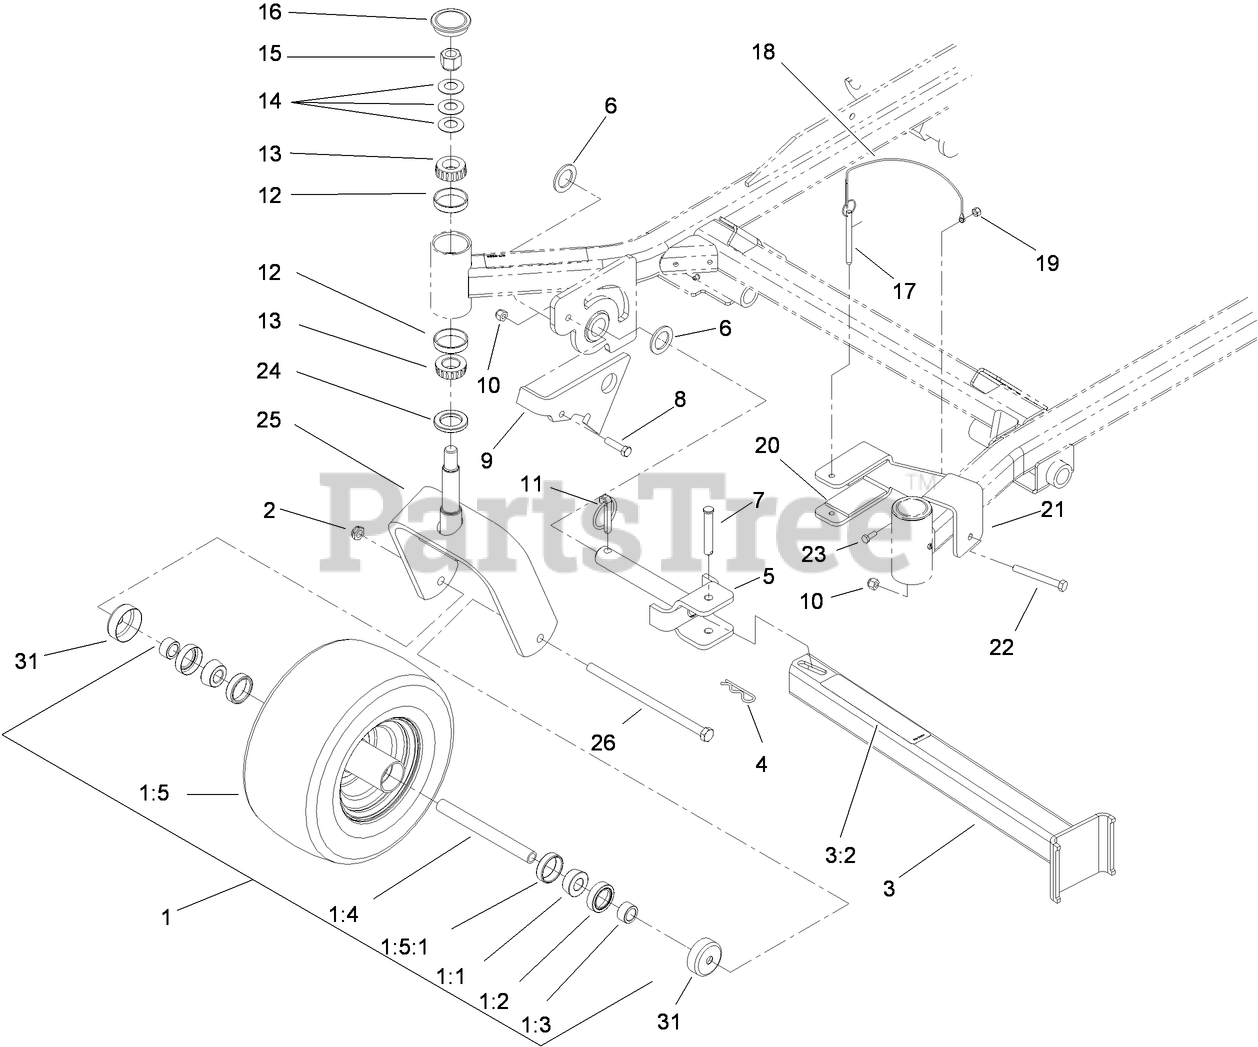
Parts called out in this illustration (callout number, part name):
1	WHEEL AND TIRE ASM
1:1	BEARING-CONE, TAPER
1:2	SEAL-CASTER
1:3	SPACER-NUT
1:4	AXLE-CASTER
1:5	WHEEL AND TIRE ASM
1:5:1	BEARING-CUP
2	NUT-LOCK, NI
3	Leg ASM
3:2	DECAL-Z STAND
4	PIN-HAIR
5	PIN-PIVOT
6	WASHER-THRUST
7	PIN-CLEVIS
8	SCREW-HH
9	BRACKET-LATCH
10	NUT-LOCK, NI
11	PIN-LYNCH
12	BEARING-CUP, TAPERED
13	BEARING-CONE, TAPERED
14	WASHER-BELLVILLE
15	NUT-LOCK, NI
16	CAP-GREASE
17	PIN-HITCH, COTTERLESS
18	LANYARD-NYLON
19	NUT-LOCK, NI
20	Cushion-Rubber
21	BRACKET-CRADLE
22	SCREW-HH
23	SCREW-HH
24	SEAL-GREASE
25	CASTER
26	SCREW-HH
31	GUARD-SEAL
